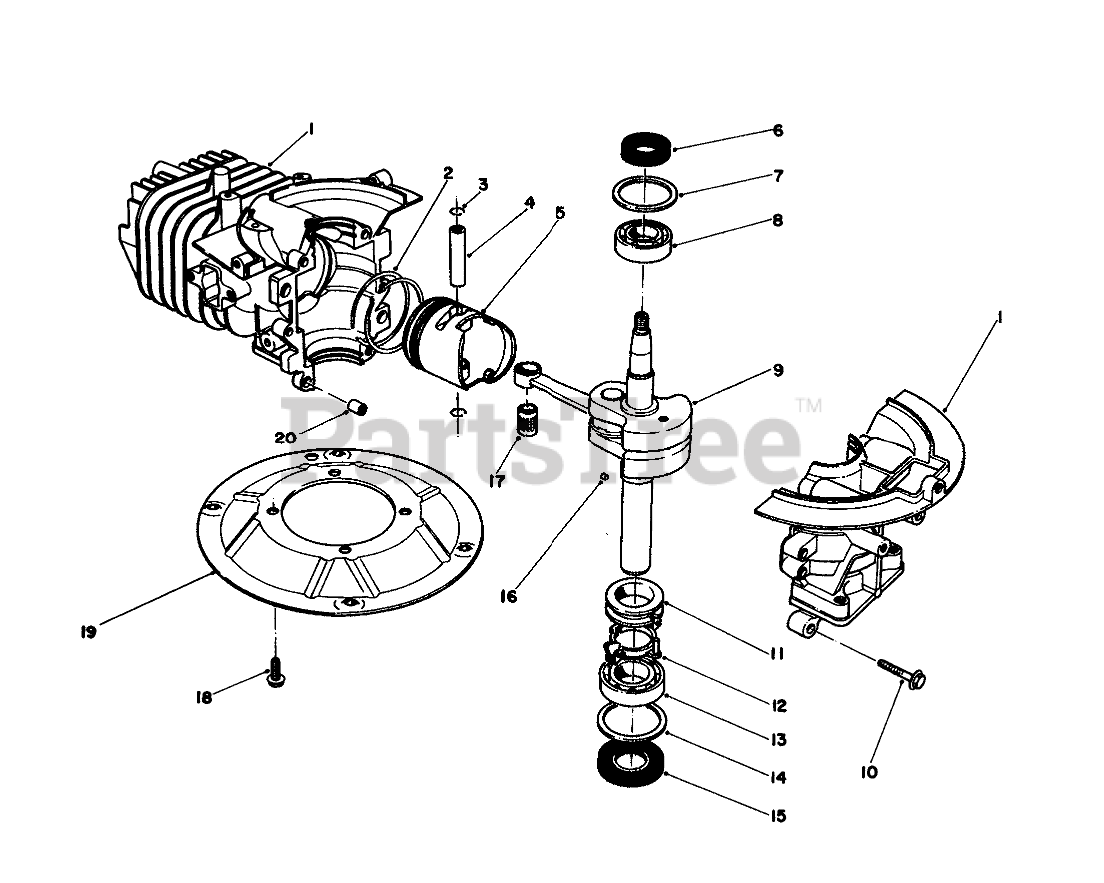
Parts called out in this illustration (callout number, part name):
1	CRANKCASE
2	RING SET
3	Circlip
4	PIN-PISTON
5	Piston
6	OIL SEAL
7	WASHER-UPPER
8	BEARING-UPPER
9	Pin-Wrist
10	E-Ring
11	SPACER
12	BRACKET
13	LOWER BRG
14	WASHER-LOWER
15	SEAL-OIL
17	BEARING
19	PLATE-MOUNTING
